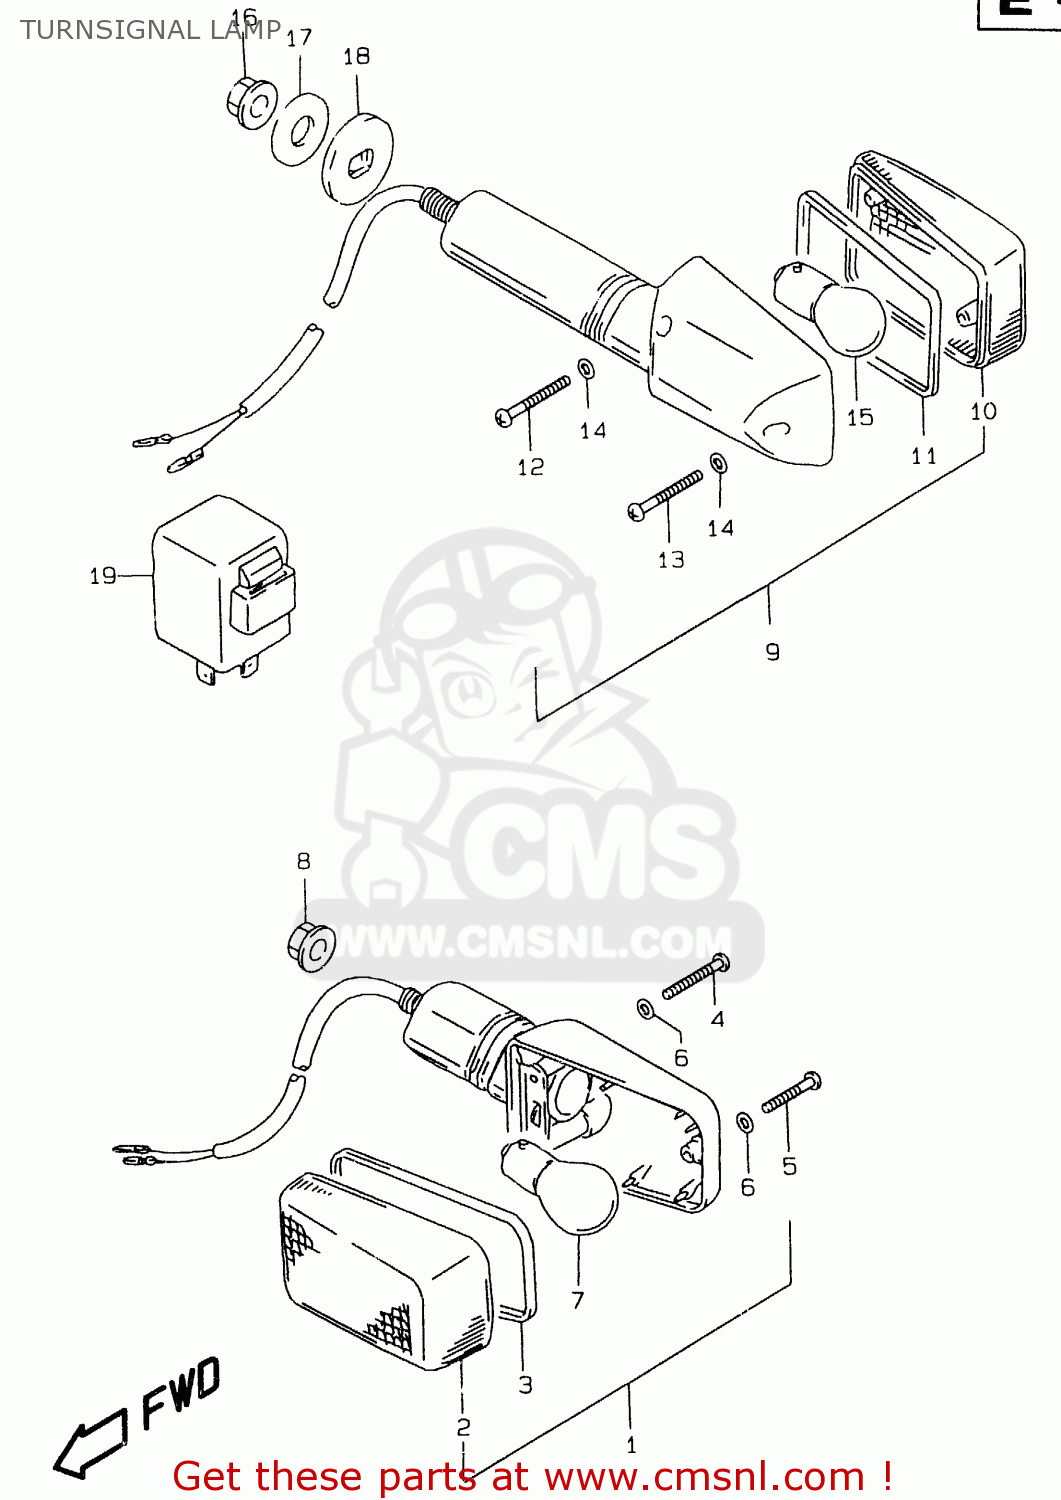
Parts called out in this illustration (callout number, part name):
1	LAMP ASSY,FR TURN SIGNAL
2	LENS
3	GASKET (NAS)
4	SCREW(3X30)
5	SCREW
6	GASKET (NAS)
7	BULB(12V21W)
8	NUT
9	LAMP ASSY,RR TURNSIGNAL
10	LENS
11	GASKET (NAS)
12	SCREW(3X30)
13	SCREW
14	GASKET (NAS)
15	BULB(12V21W)
16	NUT
17	WASHER(10.5X30X2.3)
18	SPACER,RR TURNSIGNAL
19	RELAY ASSY
